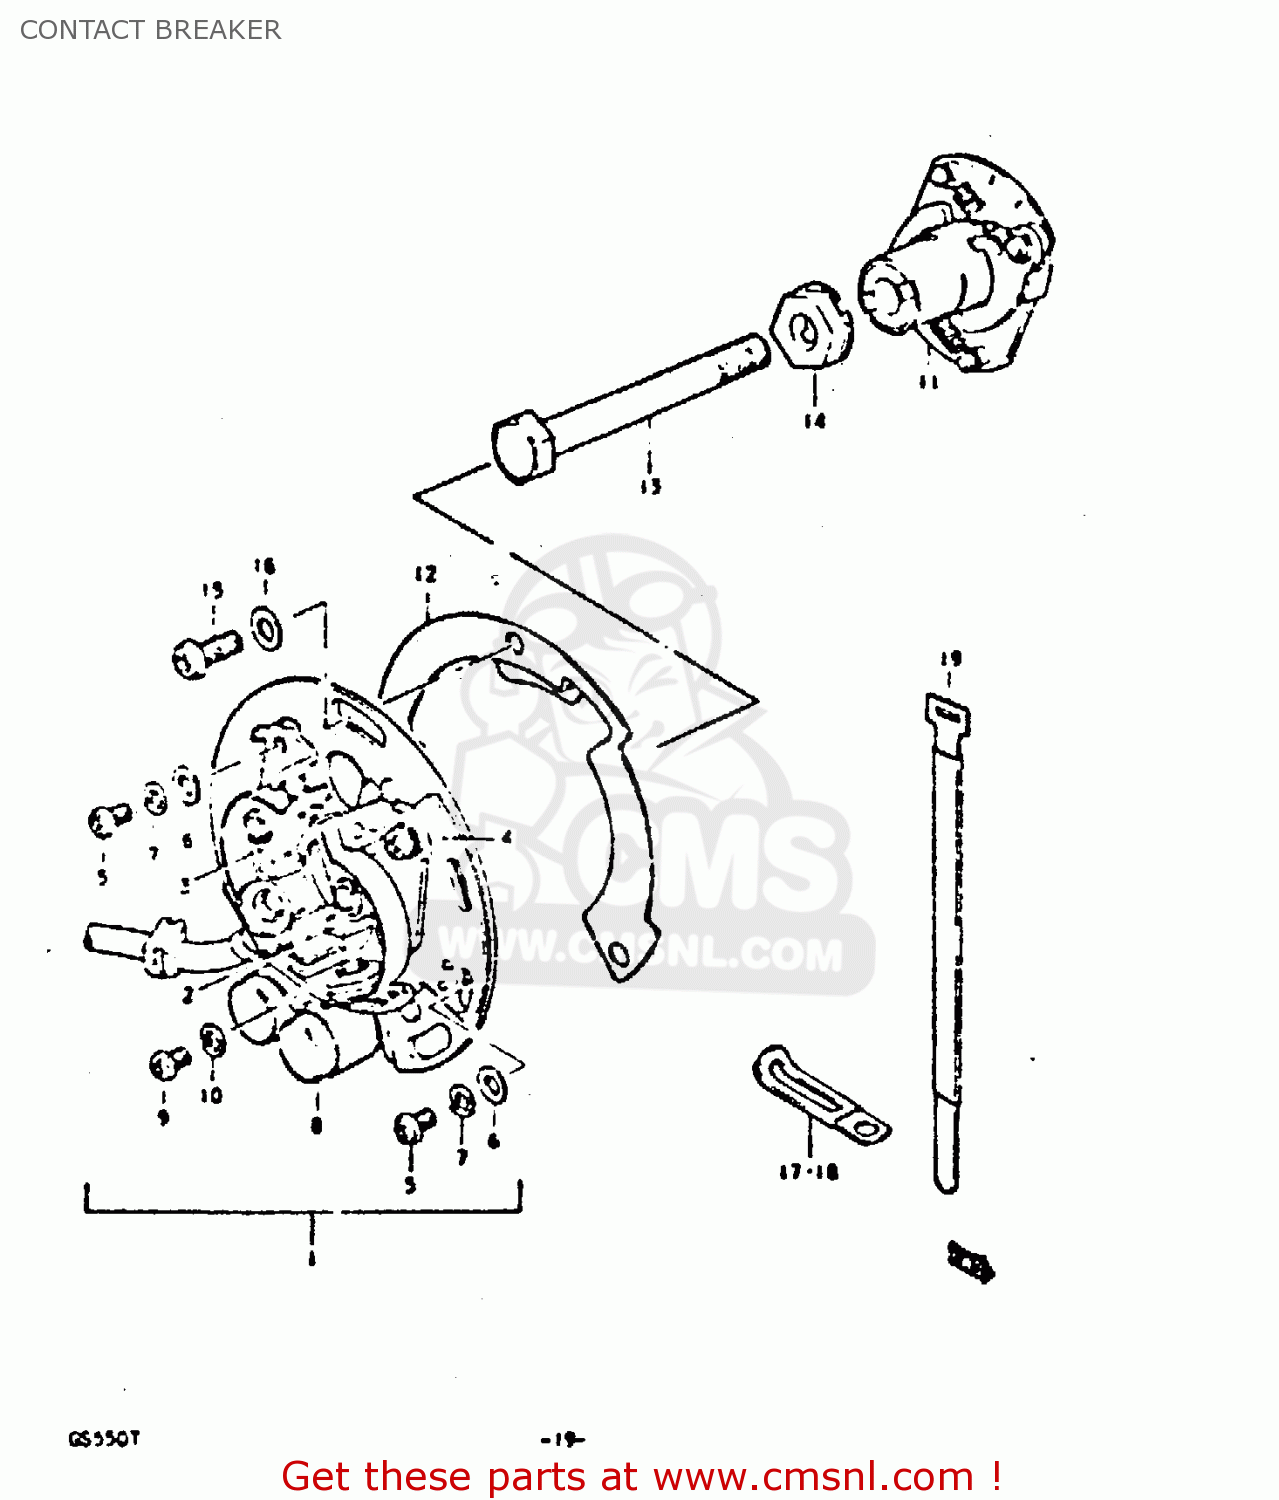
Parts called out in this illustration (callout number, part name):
1	BREAKER ASSEMBLY,CONTACT
2	POINT ASSEMBLY,CONTACT
3	POINT ASSEMBLY,CONTACT
4	PLATE,CONTACT POINT
5	SCREW 4X6
6	WASHER
7	LOCK WASHER
8	CONDENSER
9	SCREW 4X6
10	LOCK WASHER
11	GOVERNOR ASSEMBLY
12	PLATE,IGNITION TIMING
13	BOLT
14	WASHER
15	SCREW(5X12)
16	WASHER
17	CLAMP L:35
18	CLAMP
19	CLAMP
